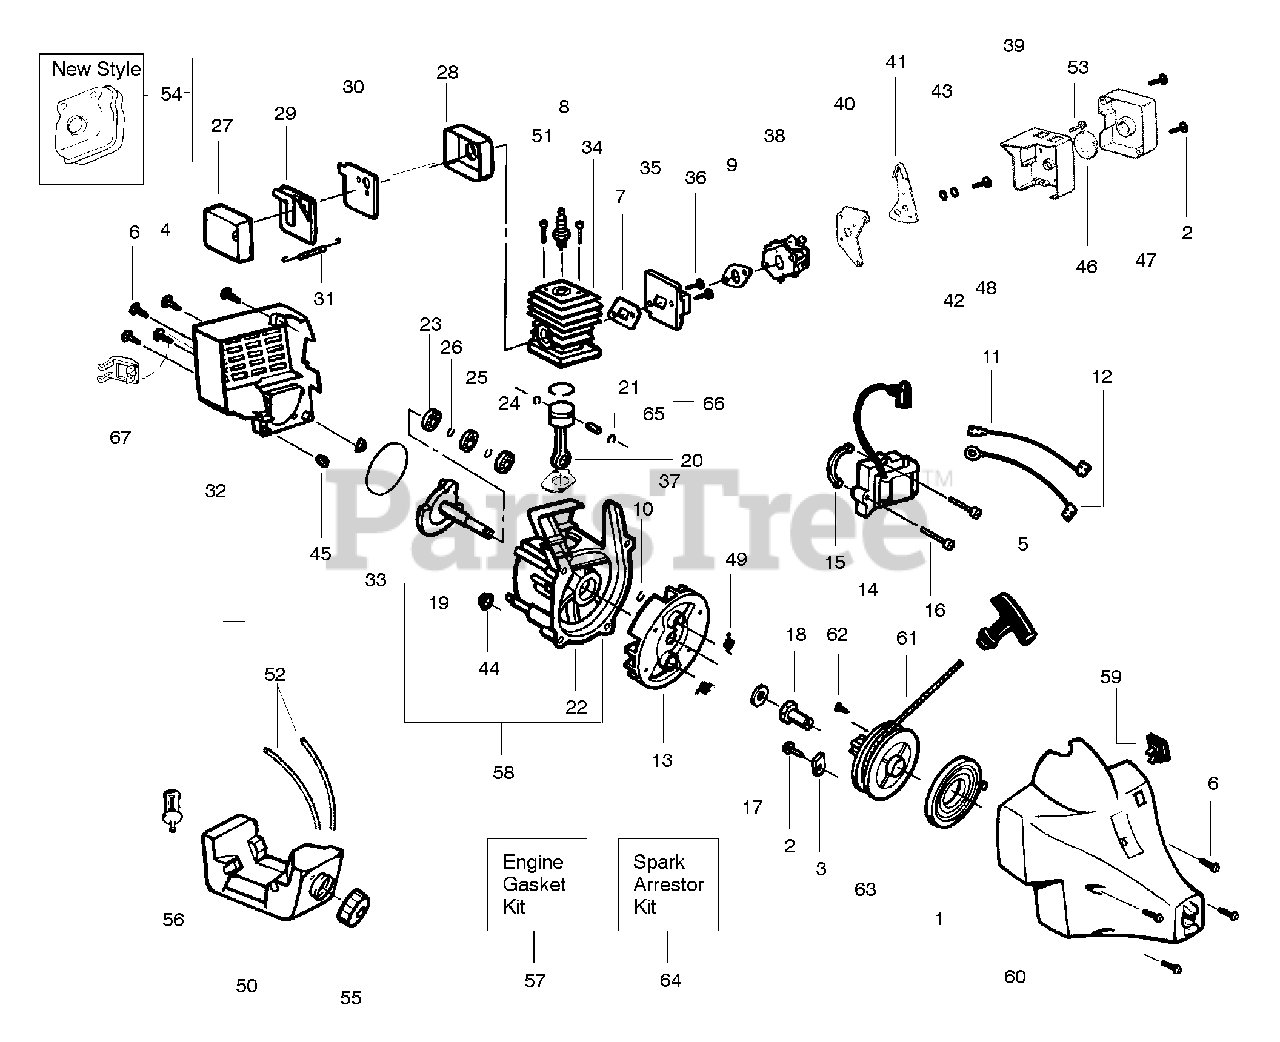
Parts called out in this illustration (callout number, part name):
1	Starter Spring
3	Retainer-Pulley
4	Screw-Shrd/Fan Hsg.
5	Starter Handle
6	Screw
7	Gasket-Cyl./Carb.(kit)
8	Spark Plug (RCJ 8Y)
9	Gasket-Carb.(kit)
10	Retainer Ring-C'shaft
11	Lead Wire
12	Ground Wire
13	Flywheel Ass'y.
14	Ignition Module
15	Spacer-Module
16	Screw-Module
17	Washer-Thrust
18	Drive Coupling
19	Crankshaft Ass'y.
20	Connecting Rod Ass'y.
21	Piston Ring
22	Crankcase Ass'y.
23	Inner Bearing
24	Outer Bearing
25	C'case Seal
26	Retain. Ring-C'case
27	Muffler Body
28	Muffler Cover
29	Muffler Baffle-Exit
30	Muffler Baffle-First
31	Muffler Spring Old Style
31	Muffler Spring New Style
32	Rear Shroud
33	Gasket-C'case (kit)
34	Cylinder Kit
35	Carb. Adaptor Kit
37	Gasket-Cylinder (kit)
38	Carburetor Ass'y Kit Walbro (WA226)
38	Carburetor Ass'y Kit Zama (C1U-W7)
40	Choke Plate
41	Choke Lever
42	Spacer-Choke
43	Wave Washer
44	Isolator-C'case
45	Isolator-Shroud
46	Air Filter Foam
47	Air Filter Cover
49	Starter Dog Spring
50	Fuel Tank Ass'y
51	Screw-Cylinder
52	Fuel Line Kit
54	Muffler Kit Old Style
54	Muffler Kit New Style
55	Fuel Cap Ass'y.
56	Fuel Pickup Ass'y.
57	Engine Gasket Kit
58	C'case & C'shaft Assy.
59	On/Off Switch
60	Fan Housing Ass'y
61	Rope Kit
63	Starter Pulley Kit
64	Spark Arrestor Kit Old Style
64	Spark Arrestor Kit New Style
65	Piston Pin Retainer
66	Piston Kit
67	Guard-Muffler
